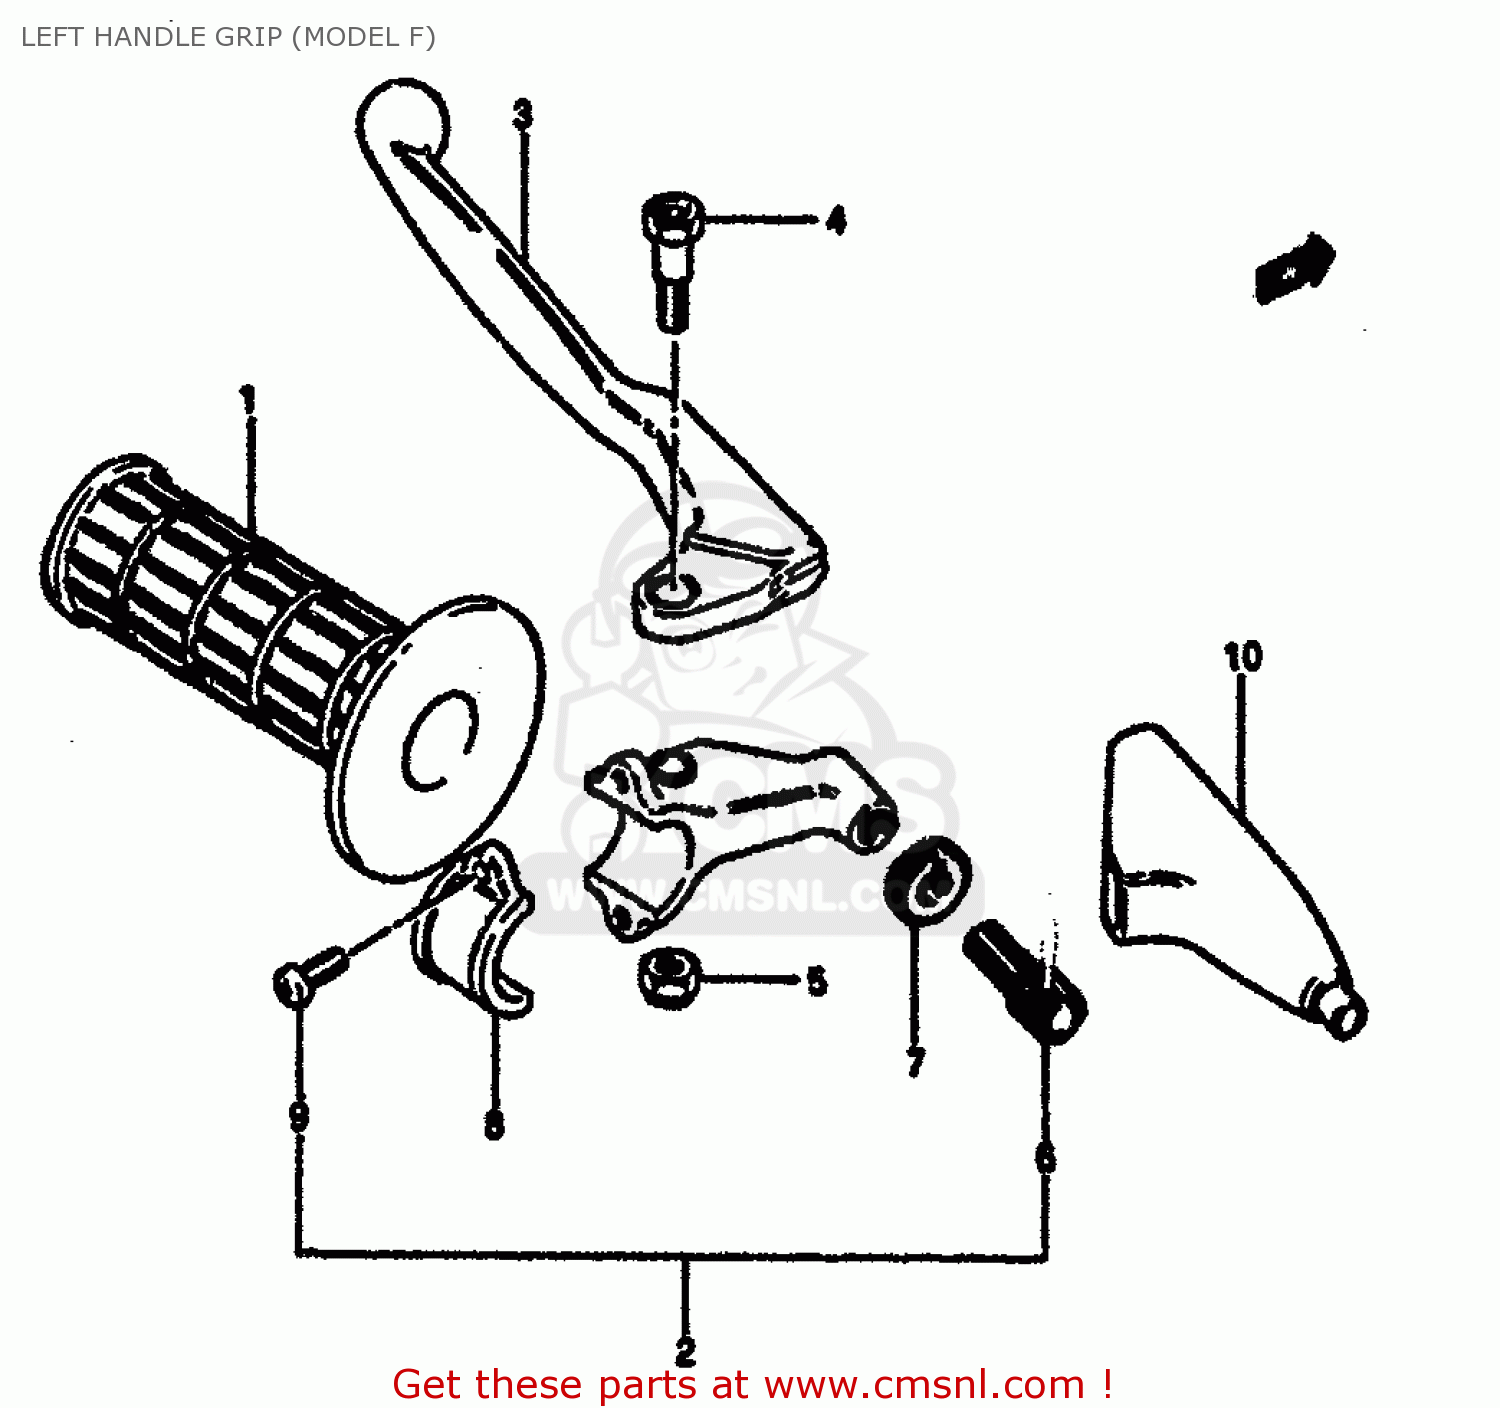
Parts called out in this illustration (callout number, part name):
1	GRIP,LEFT
2	LEVER ASSEMBLY
3	LEVER,CLUTCH
4	BOLT,LEVER
5	NUT
6	ADJUSTER,CABLE
7	NUT,CABLE ADJUSTER LOCK
8	HOLDER,LEVER
9	SCREW (5X14)
10	COVER,CLUTCH LEVER
